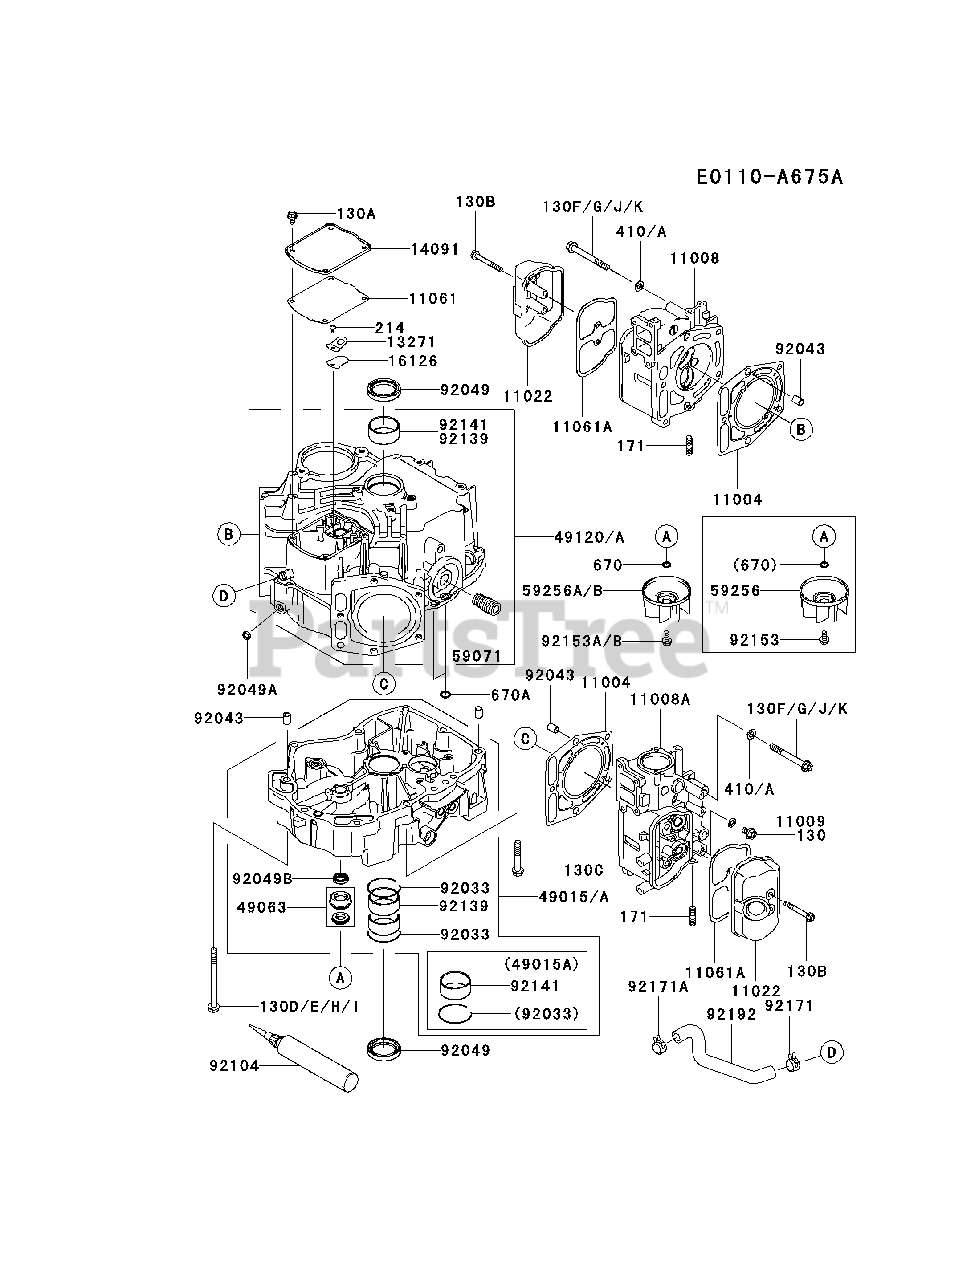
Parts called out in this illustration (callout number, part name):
130	BOLT-FLANGED,8X12
130A	BOLT-FLANGED,6X12
130B	BOLT-FLANGED,6X50
130C	BOLT-FLANGED,8X50
130H	BOLT-FLANGED,8X100
130J	BOLT-FLANGED,8X70
171	BOLT-STUD,8X18
214	SCREW-PAN+-,4X8
670	O RING,9MM
670A	O RING,11MM
92153B	BOLT,6X14
92192	TUBE,BREATHER
